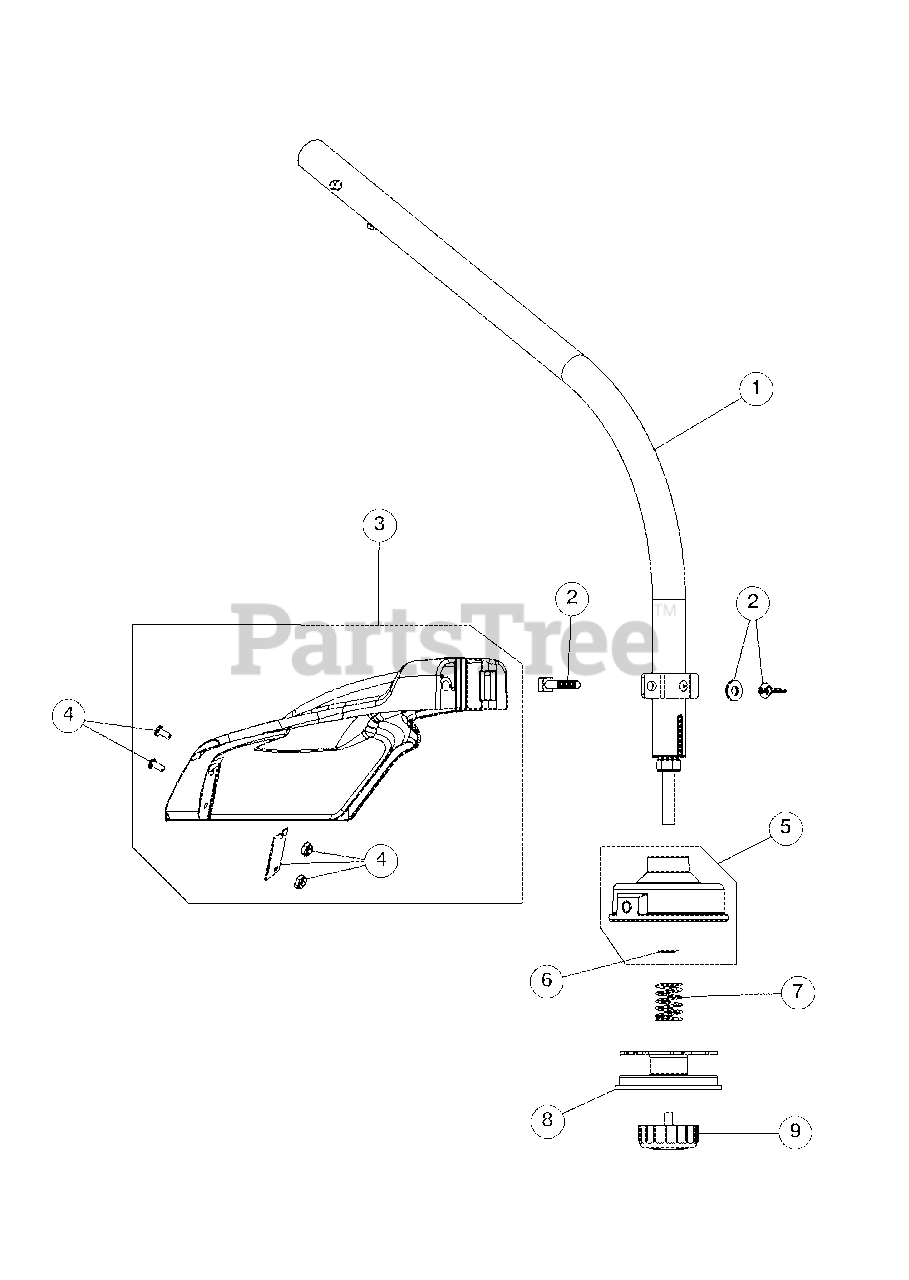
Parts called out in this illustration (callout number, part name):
1	Lower Shaft Housing Assembly
2	Shield Mounting Hardware
3	Shield Assembly (includes 4)
4	Blade Assembly
5	Outer Spool Assembly (includes 6)
6	Retainer
8	Inner Reel
9	Bump Knob Assembly
